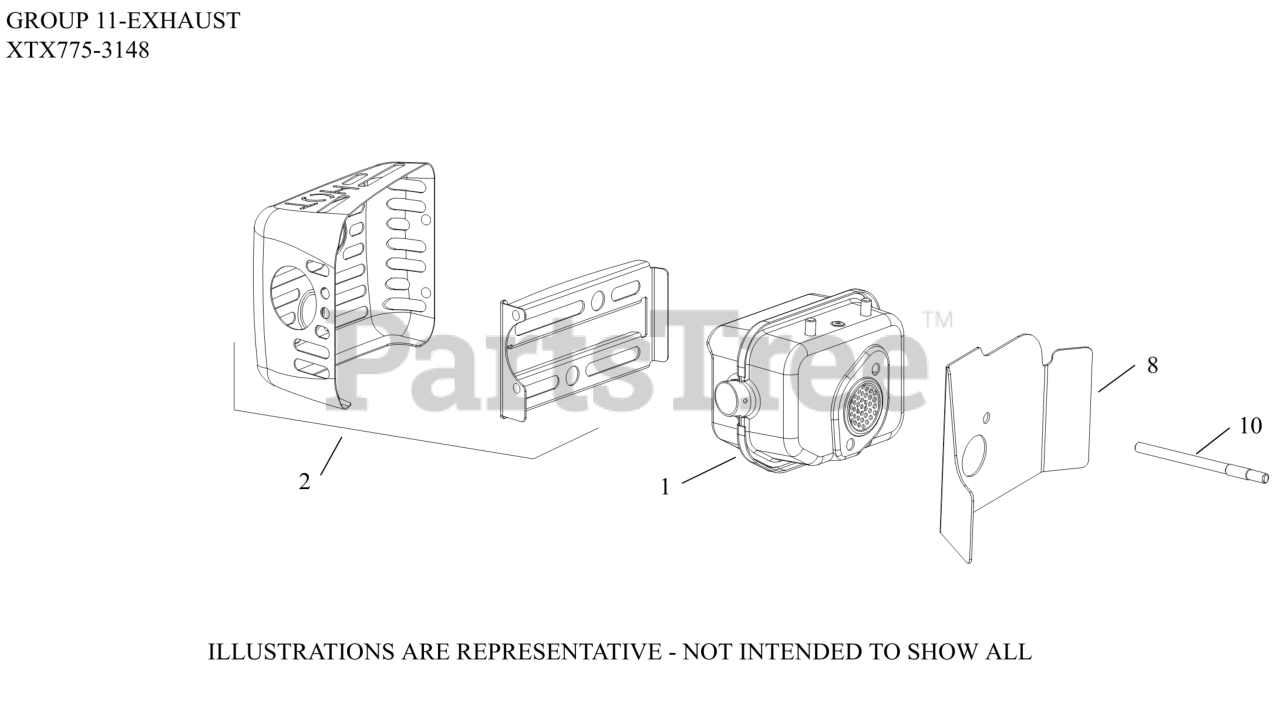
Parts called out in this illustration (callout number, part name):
1	KIT, MUFFLER
2	GUARD, MUFFLER
8	GASKET, MUFFLER (HEAT DEFLECTOR)
10	STUD (M6)
